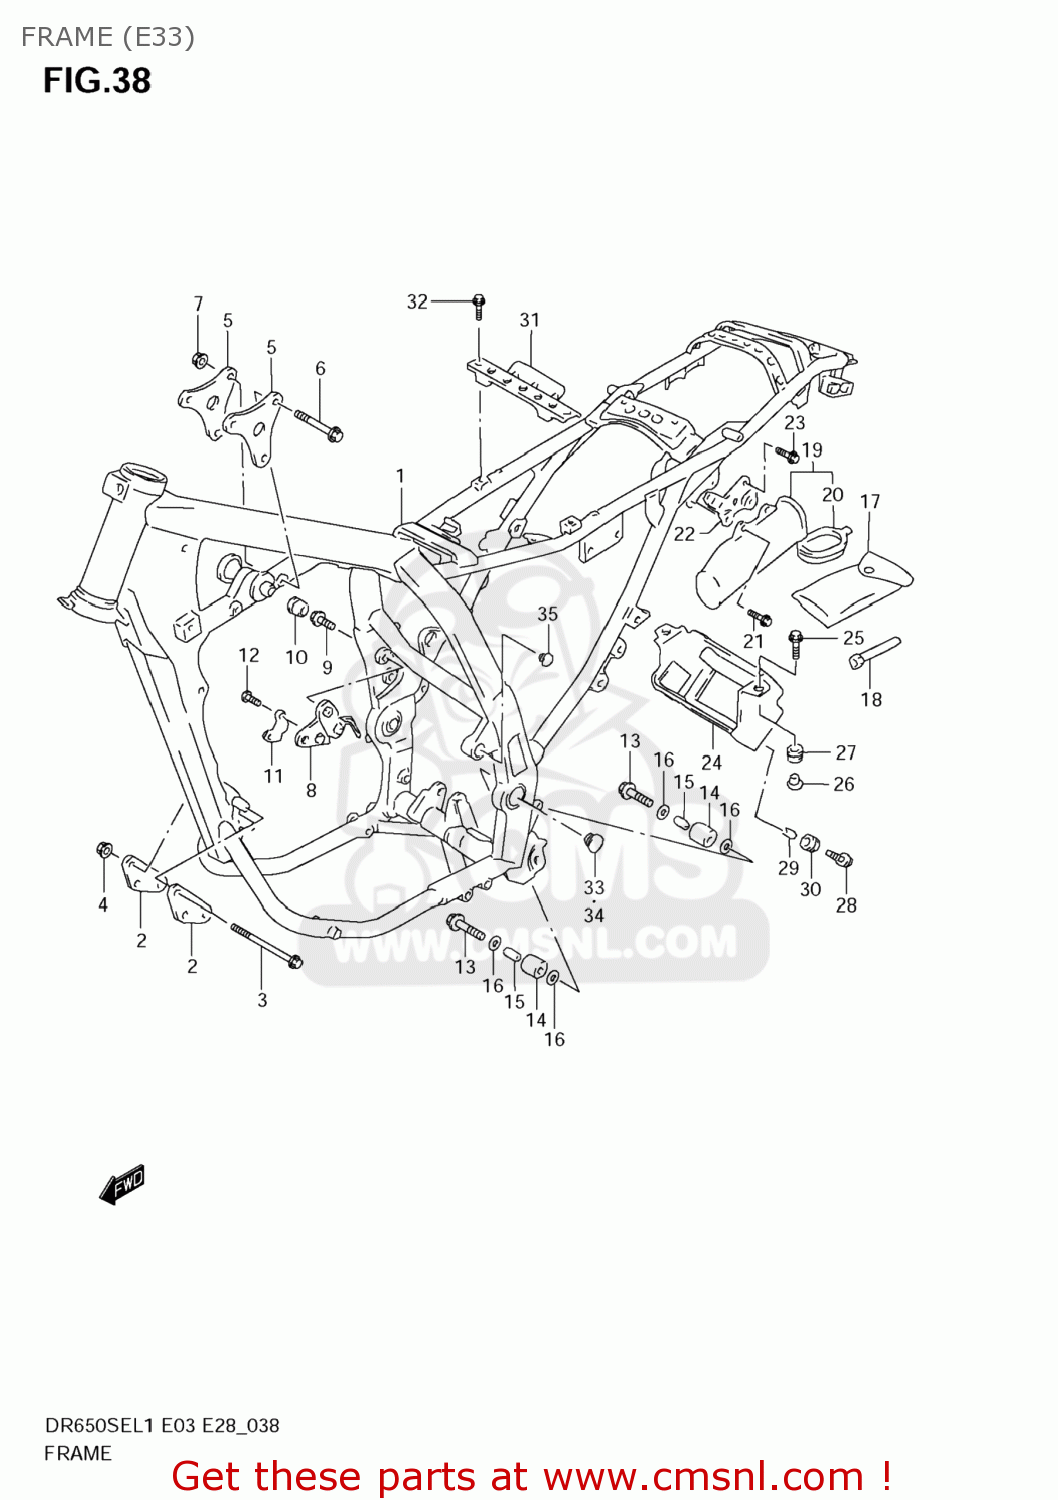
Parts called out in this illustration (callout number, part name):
1	FRAME(GRAY)
2	PLATE,ENG MTG FR
3	BOLT(8X100)
4	NUT
5	PLATE,ENG MTG UPR
6	BOLT(8X55)
7	NUT
8	PLATE,ENG MTG RR,R
9	BOLT
10	PLUG(OD:22)
11	BRACKET,STOP SWITCH
12	SCREW
13	BOLT(8X38)
14	ROLLER,CHAIN CONTROL UPR
15	SPACER(8.6X12X25.5)
16	WASHER
17	TOOL ASSY
18	SPARK PLUG WRENCH(16)
19	HOLDER,TOOL
20	CAP,HOLDER
21	BOLT(6X16)
22	BRACKET,TOOL HOLDER
23	BOLT
24	HOLDER,BATTERY
25	BOLT(6X20)
26	WASHER
27	CUSHION
28	BOLT(6X16)
29	SPACER(6.1X9X7.5)
30	CUSHION
31	PLATE,BATTERY FITING
32	BOLT
33	PLUG,FRAME PIVOR,R
34	PLUG,FRAME PIVOR,L
35	PLUG,FRAME BOSS
